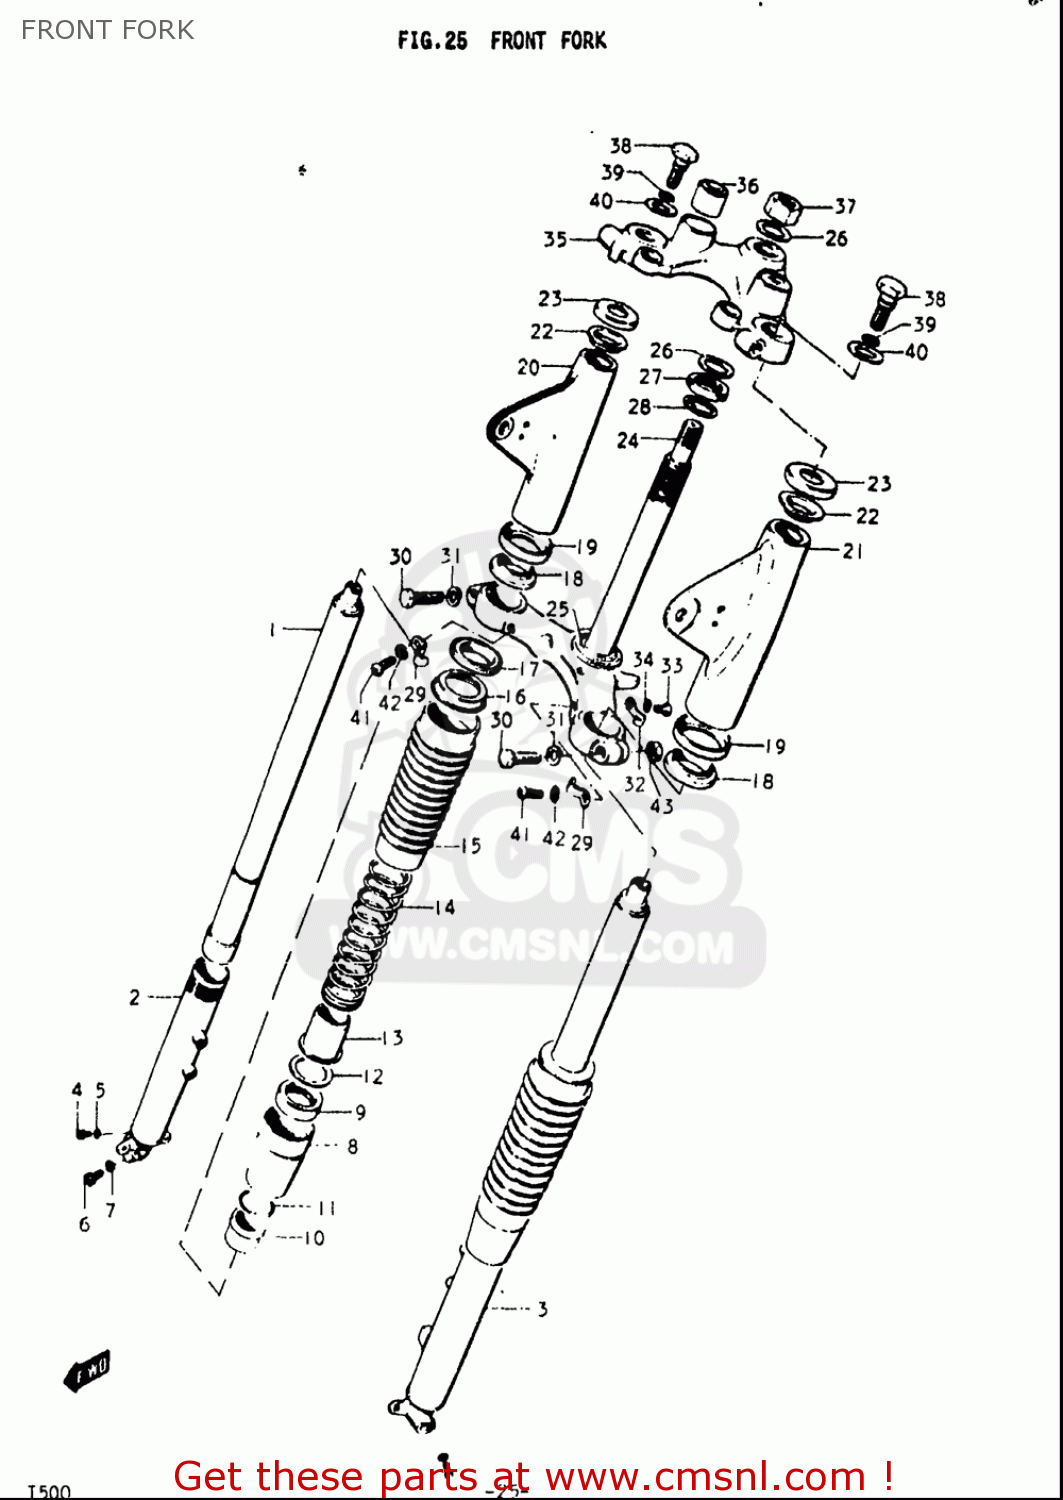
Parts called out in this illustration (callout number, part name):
4	OIL DRAIN PLUG
5	GASKET,DRAIN,PLUG (NAS)
6	BOLT
7	WASHER,LOCK
9	SEAL,OIL
12	WASHER
15	BOOT,SPRING COVER
18	CUSHION,HEADLAMP BRACKET
19	SEAT,HEADLAMP BRACKET
30	BOLT,FORK INNER TUBE F
31	WASHER,LOCK
32	CLIP,BRAKE CABLE
33	SCREW
34	WASHER,LOCK
37	NUT
38	CAP,FORK INNER TUBE
40	WASHER
41	SCREW
42	WASHER,LOCK
43	NUT
